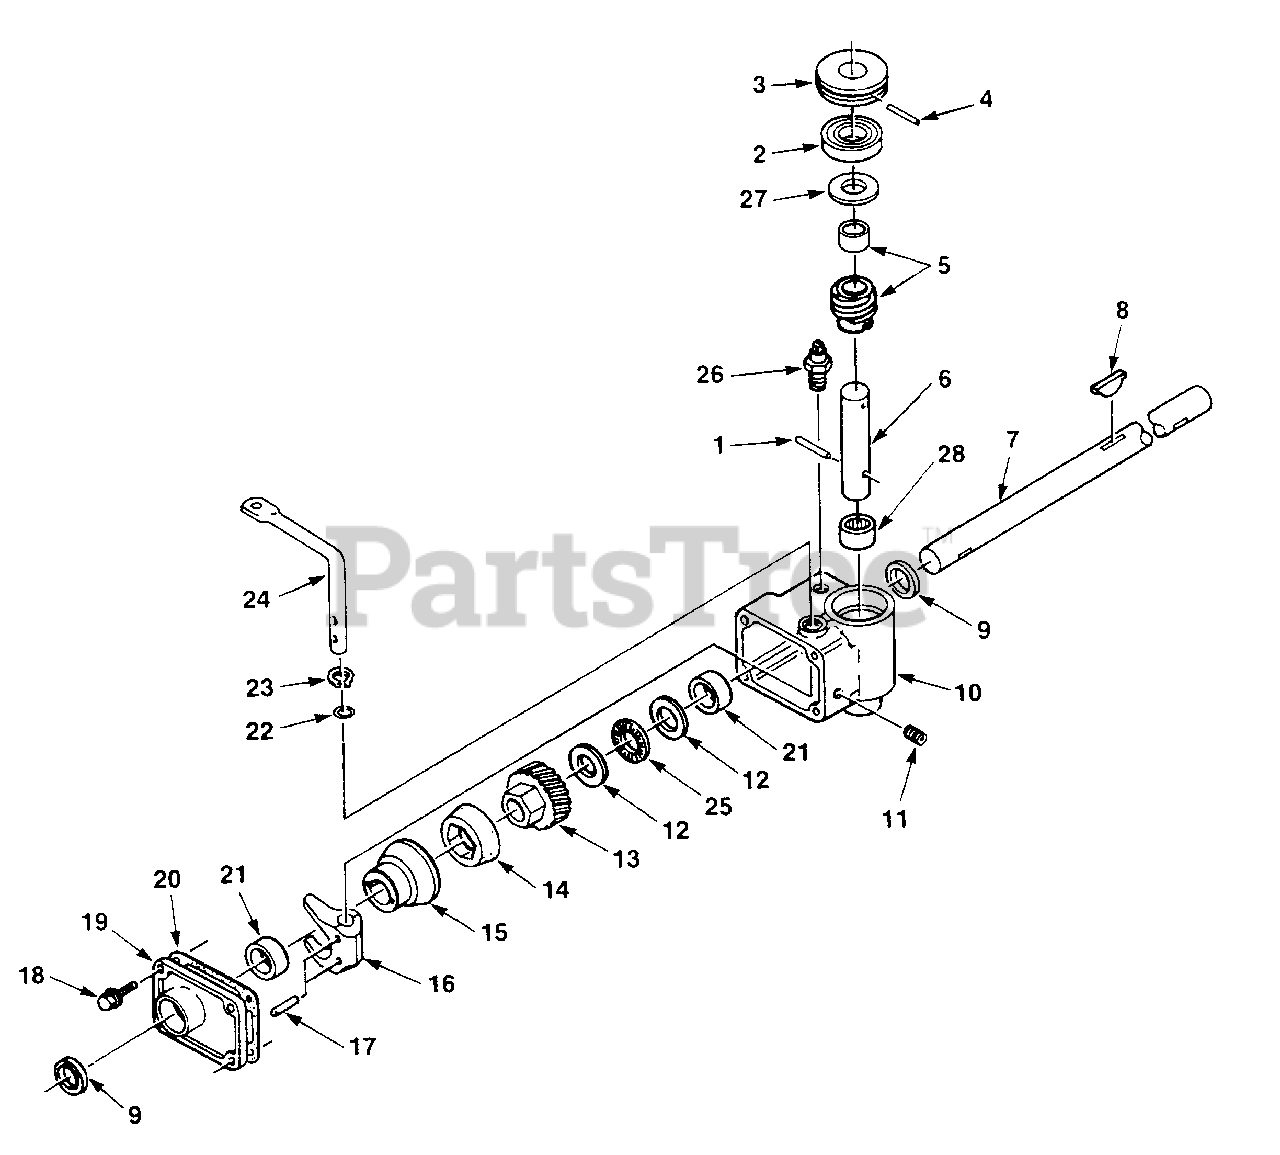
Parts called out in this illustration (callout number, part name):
3	PULLEY
5	WORM & SPACER
6	SHAFT- Worm
7	SHAFT- Drive
10	GEAR REDUCER HOUSING ASSY.
12	RACE- Bearing
13	GEAR- Helical
14	CONE- Friction
15	DRUM- Clutch
16	FORK- Shift
19	COVER- Gearbox
20	GASKET
21	BUSHING- Sleeve
24	LEVER- Shift
25	BEARING- Thrust
28	BEARING- Needle
